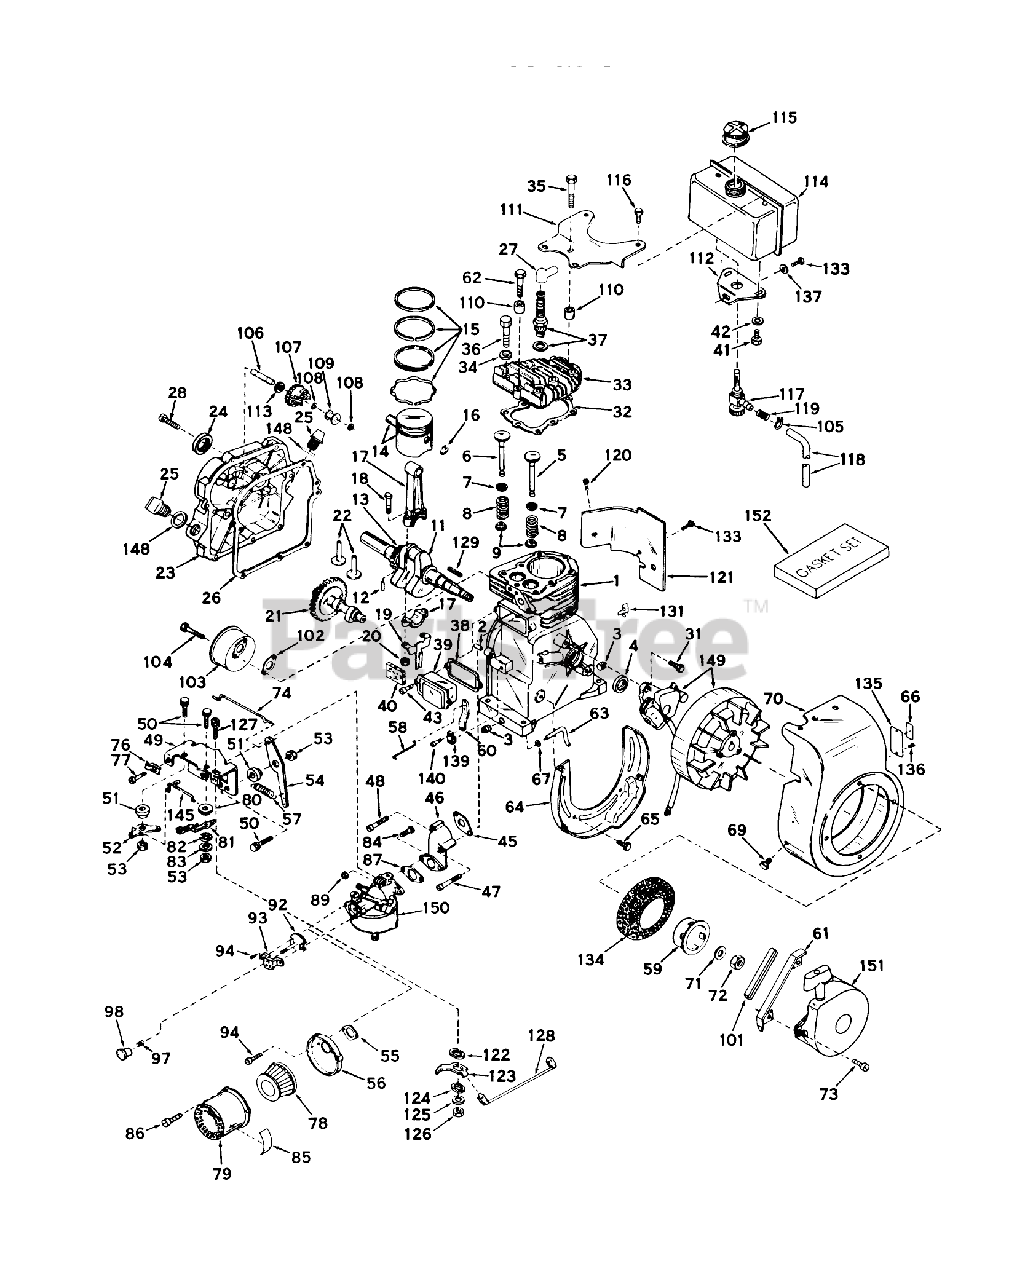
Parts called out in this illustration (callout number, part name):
1	Cylinder Assy., (Incl. Nos. 2, 3 4)
2	Pin-Dowel
3	Plug-Drain, Oil (SQH 1/4-18)
4	OIL SEAL
5	Valve, Intake (Incl. Ref. #38, 39 40) (Std.)
5	Valve, Intake(1/32"overs.)(Incl. Ref. 8, 9 10)
6	Valve, Exhaust (Standard)(Incl. Ref. 8, 9 10)
6	Valve, Exhaust (1/32" Overs.(Incl. Ref. 8, 9 10)
7	Cap-Upper Valve Spring
8	Spring-Valve
9	Cap-Valve, Spring
11	Crankshaft Assy. (Incl.Nos. 12 13)
12	Pin, Groove
13	Gear, Crankshaft
14	Piston Pin Assy. (Incl. 2 of No. 16)(Standard)
14	Piston Pin Assy. (Incl. 2 of No. 16)(.010 oversize)
14	53020 ADN. TO 28594
15	Piston Ring Set Std.
15	Piston Ring Set .010 O.S.
15	Piston Ring Set .020 O.S.
16	Ring-Retaining, Piston Pin
17	Rod Assy., Connecting (Incl. Ref. 18, 19 20)
18	Bolt, Connecting
19	53020/22 GIL.HYDRO
20	LOCKNUT
21	Camshaft
22	Lifter-Valve
23	Cover, Cylinder (Incl. Ref. 24 106)
24	Seal, Oil
25	Plug-Fill, Oil
26	Gasket-Cylinder Cover
27	Cover-Spark Plug
28	Screw
31	Screw
32	Gasket, Cylinder Head
33	CYLINDER HEAD
34	Washer
35	Screw
36	Screw
37	SPARK PLUG
38	Gasket Breather
39	Breather Assembly (Incl. Nos. 52 84)
40	Element-Breather
41	Screw
42	Washer
43	Screw
45	Gasket-Intake
46	INTAKE PIPE
47	Screw
48	Screw
49	Bracket, Speed Control
50	SCREW, HEX WASHER HD.
51	Bushing
52	Lever, RPM Adjusting
53	Nut
54	Lever, Bell Crank
55	Gasket
56	Bracket
57	Spring-Extension
58	Jet-Main
59	Starter Cup
60	Lever-Governor
61	Guard, Starter
62	Screw
63	Rod-Governor
64	Baffle, Blower Hsg.
65	Screw (1/4-20x19/32)
66	INSTRUCTION DECAL
67	Washer-Flat
69	Screw
70	Housing,Blower
71	Washer
72	Hex Nut
73	Screw
74	Link, Bell Crank
76	Conduit
77	Screw (10-32 x 3/8)
78	Element
79	Body
80	Bushing Control Lever
81	Lever, Control
82	Washer
83	Washer, Flat
85	Decal
86	Screw
87	Gasket
89	Nut and Lock Washer (1/4-28)
92	Plate, Choke
93	Bracket-Choke
94	Screw, Phil. Fil. Hd. Sems
97	Spring, Compression
98	Knob, Choke
101	Seal, Snowguard
102	Gasket Exhaust
103	Muffler
104	Screw, Hex Hd. Cap
105	Clamp-Line, Fuel
106	Shaft-Governor
107	Governor Gear ASM
108	Ring-Retaining
109	Spool-Governor
110	pacer
111	Bracket, Fuel Tank-Upper
112	Bracket, Fuel Tank Lower
113	Washer-Flat
114	Tank Assy., Fuel (Incl. Ref. 112 115)
115	Cap, Fuel Tank
116	Screw
117	Fitting Shut-off, Fuel
118	Line-Fuel
119	Spring, Coil
120	Screw
121	Extension-Blower
122	Washer, Insulating
123	Terminal
124	Washer, Insulating
125	Washer, Flat
126	Nut
127	Screw, Hex Slotted Hd.
128	Wire, Ground
129	Key Flywheel
131	Clip-Wire
133	Screw
134	Screen, Air
135	IDENTIFICATION PLATE
136	DRIVE STUD
137	Washer
139	Clamp-Lever, Governor
140	Screw
145	Link, RPM Adjusting
148	Gasket
149	Magneto
150	Carburetor
151	Starter, Rewind
152	Gasket Set
